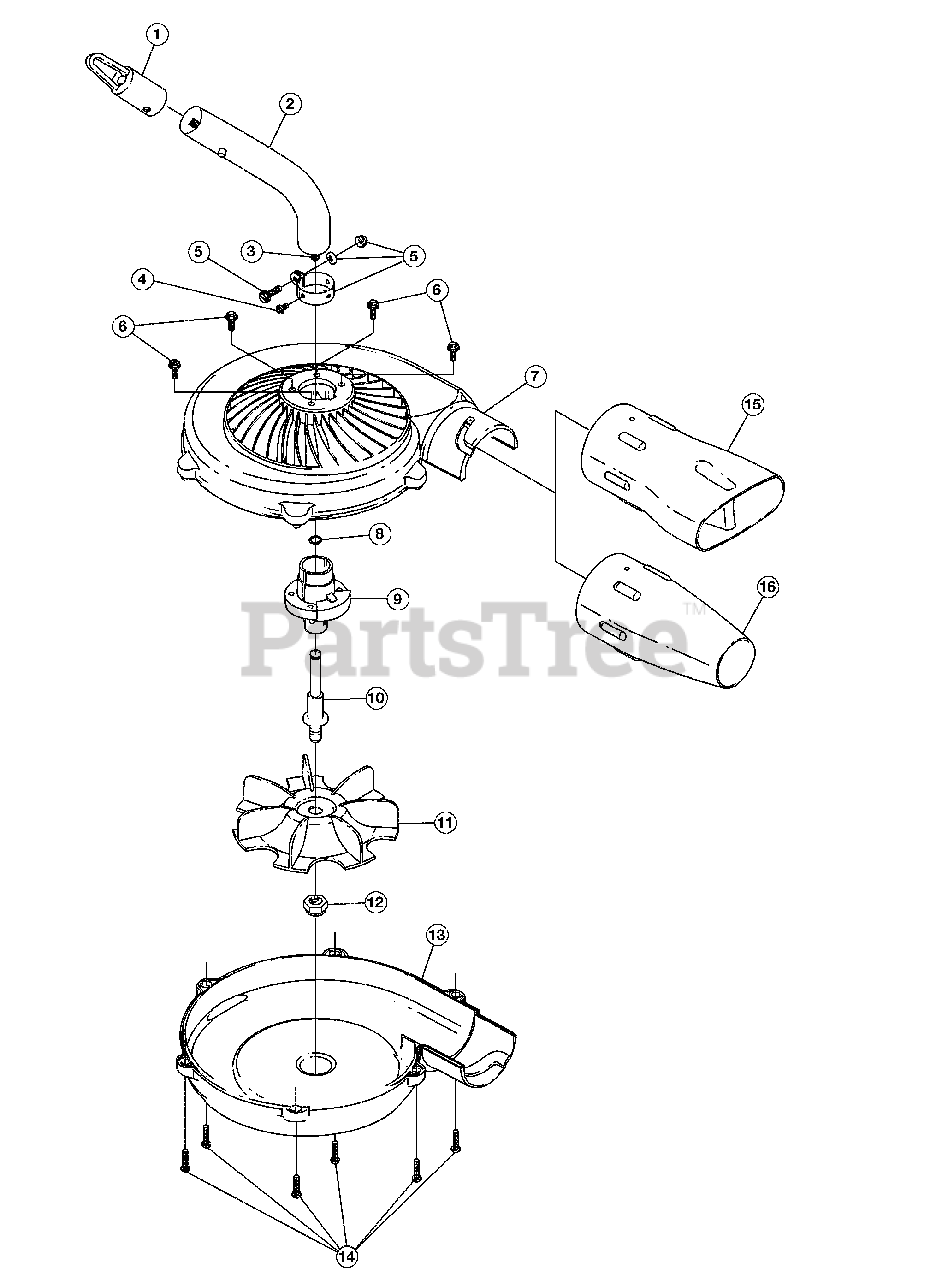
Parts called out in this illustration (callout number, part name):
1	Hanger
2	Drive Shaft Housing Assembly
3	Drive Shaft Assembly
4	Anti-Rotation Screw
5	Lower Clamp Assembly (includes 4)
6	Mounting Screw
7	Upper Housing
8	Palnut
9	Bushing Assembly Housing
10	Shaft Impeller
11	Impeller
12	Nut and Washer
13	Lower Housing
14	Mounting Screw
15	Flare Nozzle
16	Concentrator Nozzle
